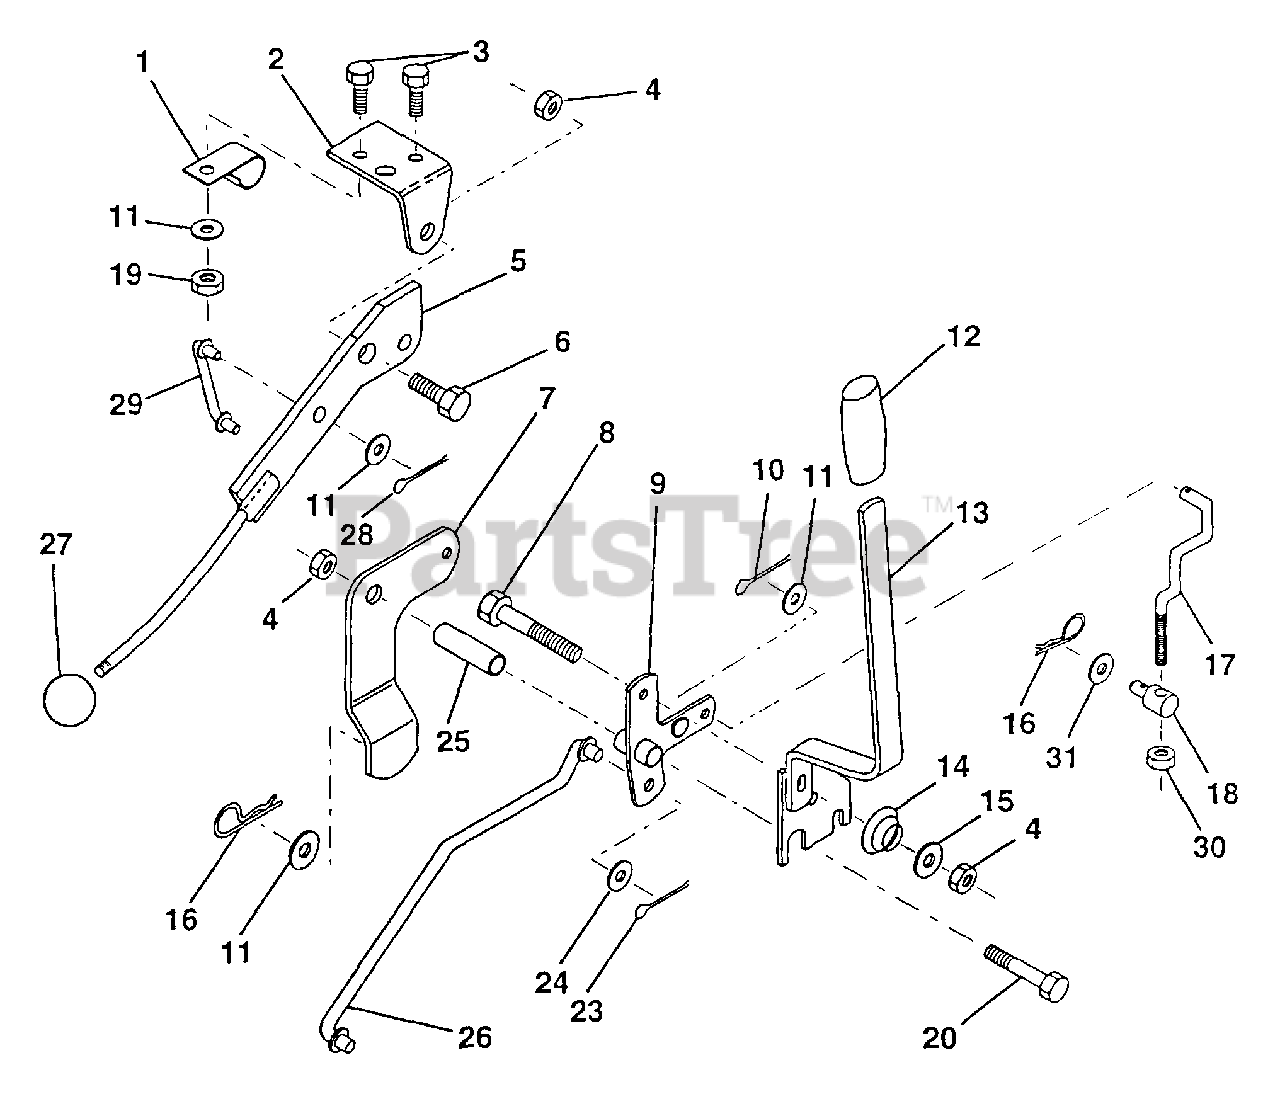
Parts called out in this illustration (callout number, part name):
1	Clip, Insulated
2	Bracket, Mower Clutch
3	Bolt, Fin. Hex 1/4-20 UNC x 1/2 Gr. 5
4	Nut, Crownlock 3/8-16
5	Assembly, Clutch Lever
6	Bolt, Shoulder
7	Assembly, Mower Clutch Arm
8	Bolt, Hex 3/8-16 UNC x 2-1/4
9	Assembly, Bellcrank Lift
10	Pin, Cotter 1/8 x 3/4
11	Washer 13/32 x 13/16 x 16 Ga.
12	Grip, Handle (AYP part number)
13	Assembly, Lift Handle
14	Spring, Compression
15	Washer 13/32 x 3/4 x 12 Ga.
16	Retainer, Spring
17	Link, Front Lift
18	Trunnion, Threaded 3/8-16
19	Nut, Crownlock 1/4-20 (AYP part number)
20	Bolt, Fin. Hex 3/8-16 UNC x 2-3/4
23	Pin, Cotter 1/8 x 1
24	Washer 17/32 x 1 x 12 Ga.
25	Tube, Spacer
26	Rod, Mower Lift
27	Knob
28	Pin, Cotter 3/32 x 3/4
29	Link, Mower Clutch
30	Nut Hex Jam 3/8-16 x 1.30
31	Washer 13/32 x 1-1/4 x 12 Ga.
